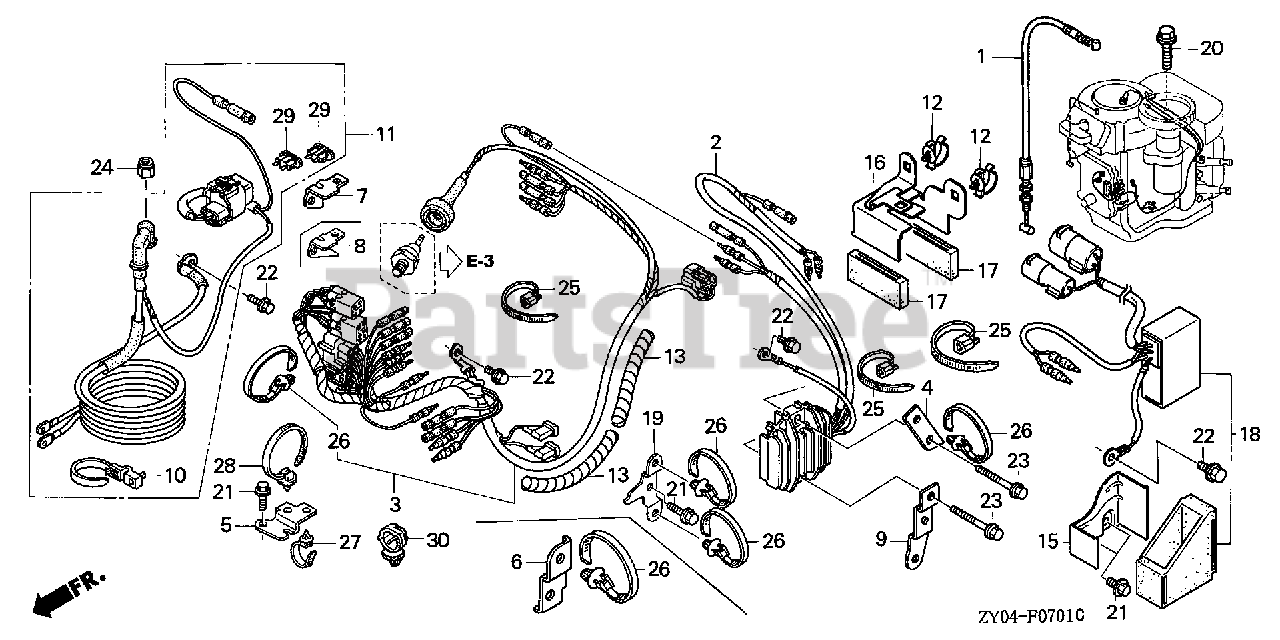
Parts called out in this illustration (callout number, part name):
1	CABLE, NEUTRAL STARTING
2	RECTIFIER ASSY., REGULATOR
3	WIRE HARNESS ASSY. (REMOTE CONTROL)(PT)
4	BRACKET, CLIP F
5	BRACKET, STARTER CABLE
8	BRACKET, FUSE CASE (PT)
9	BRACKET, E-CLIP
10	BAND, WIRE
11	CABLE ASSY., STARTER (PT)
12	CLAMP, WIRE
13	TUBE, SPIRAL A
15	BRACKET, RELAY (PT)
16	BRACKET, CONNECTOR A
17	GROMMET, CONNECTOR
18	RELAY ASSY., POWER TILT
19	BRACKET, HARNESS CLIP
20	BOLT, FLANGE (6X20)
21	BOLT, FLANGE (6X14) (CT200)
22	BOLT, FLANGE (6X12)
23	BOLT, FLANGE (6X26) (CT200)
24	NUT, LOCK (6MM)
25	TIE, CABLE
26	CLIP, HARNESS BAND (151.5MM) (NATURAL)
27	BAND, WIRE HARNESS (123.5MM) (BLUE)
28	BAND, WIRE HARNESS (93.5MM) (WHITE)
29	FUSE, BLADE (20A)
